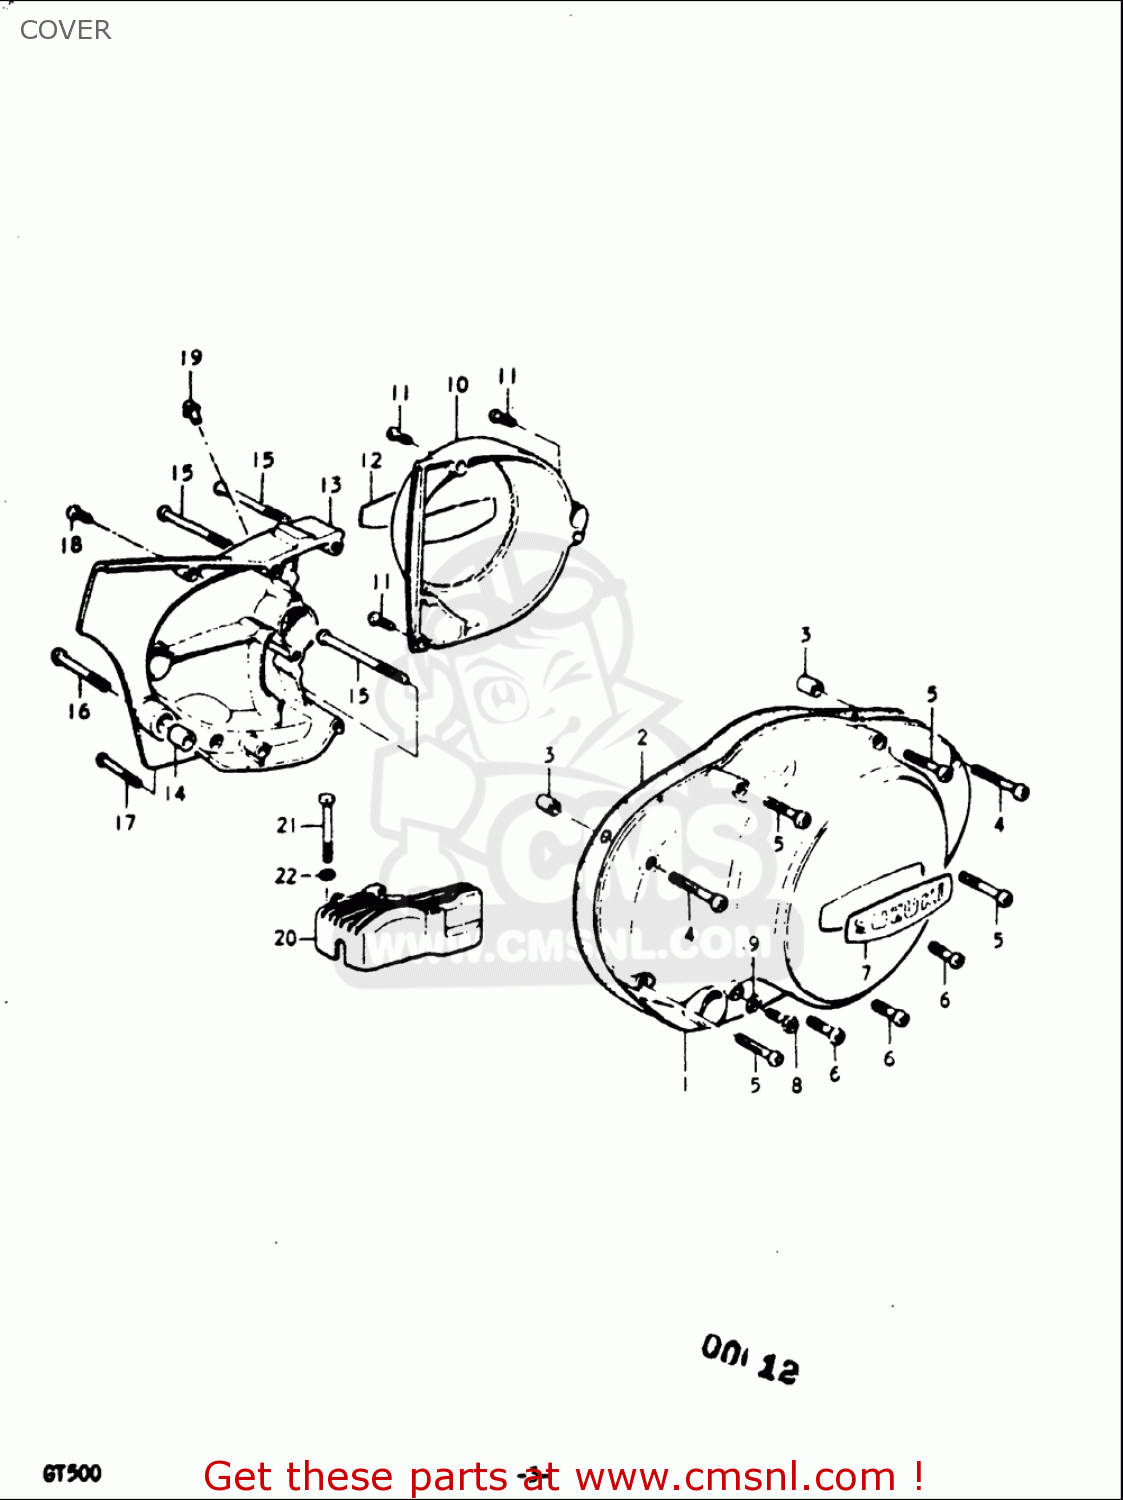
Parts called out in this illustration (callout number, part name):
2	GASKET,CLUTCH COVER (NAS)
3	PIN
4	SCREW
5	SCREW
6	SCREW
7	EMBLEM,GENERATOR COVER
8	SCREW(6X10)
9	GASKET(6.2X11X1) (NAS)
11	SCREW
12	EMBLEM,CONTACT BREAKER CAP
14	PIN
15	SCREW
16	SCREW
17	SCREW
18	SCREW
19	NIPPLE
21	BOLT(6X35)
22	WASHER
